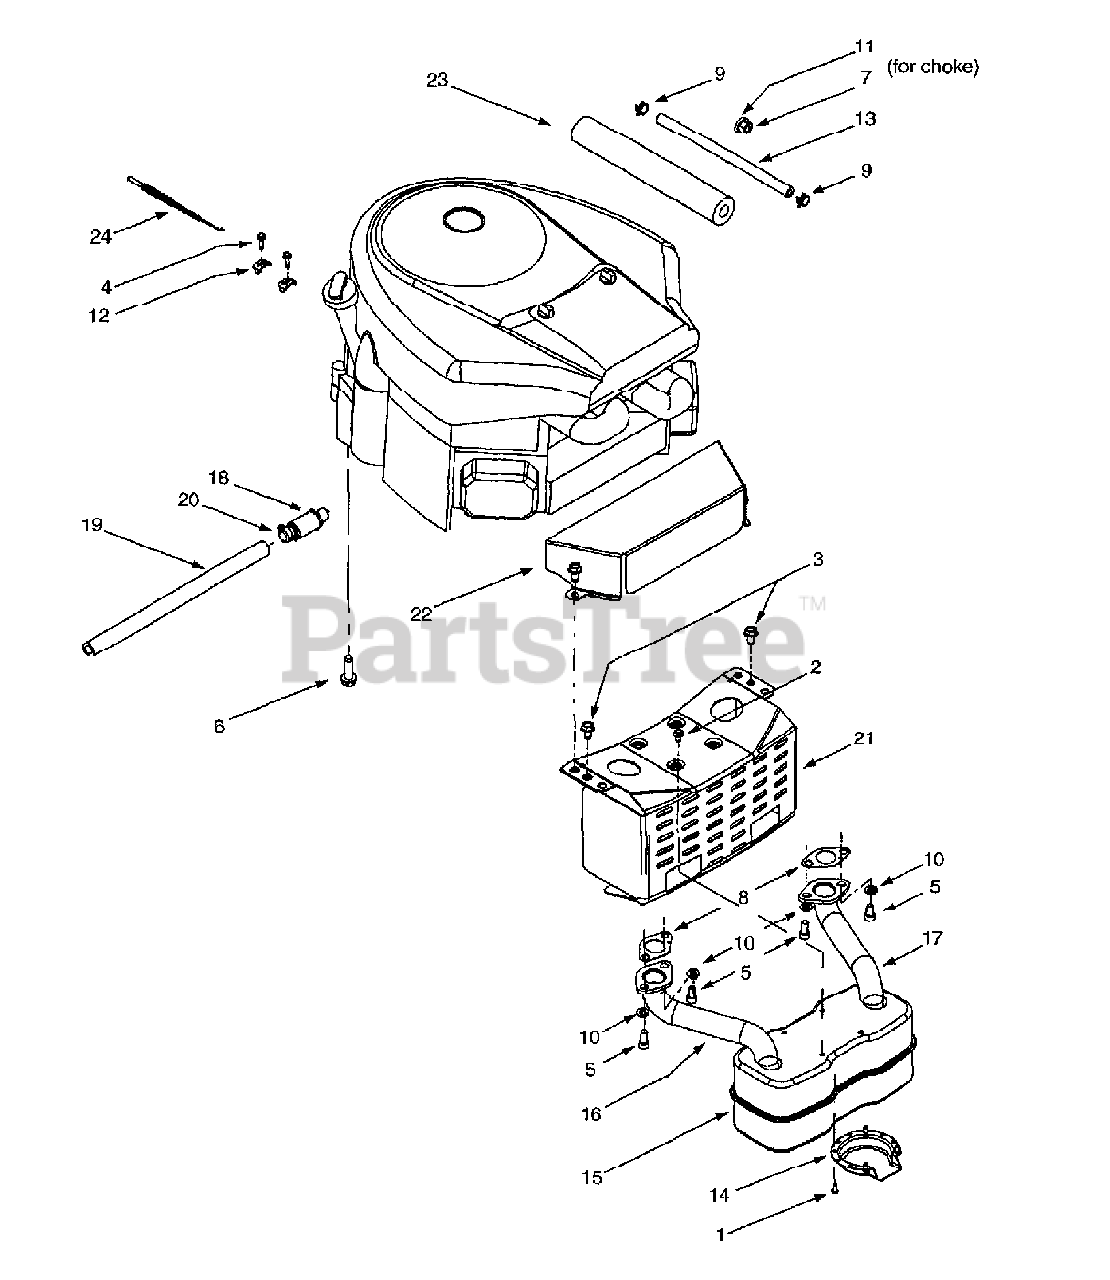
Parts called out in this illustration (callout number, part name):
1	Self-tapping Screw, #8-18 x .5
2	Self-tapping Screw, 1/4-20 x.5
3	Self-tapping Screw, 5/16-18 x .625
4	Screw, #10-32 x .625
5	Socket Cap Screw, 5/16-18 x .625
6	Self-tapping Screw, 3/8-16 x 1.25
7	Hex Nut, 3/8-16
8	Exhaust Gasket
9	1 lose clamp
10	Lock Washer, 5/16
11	Flat Washer
12	Casing Clamp
13	Fuel Line Hose
14	Muffler Deflector
15	Muffler, Twin Inlet
16	RH Exhaust Pipe
17	LH Exhaust Pipe
18	Oil Drain Valve
19	Oil Drain Hose
20	Oil Drain Cap
22	Engine Heat Shield
23	Foam (fits over fuel line)
24	Throttle Cable
